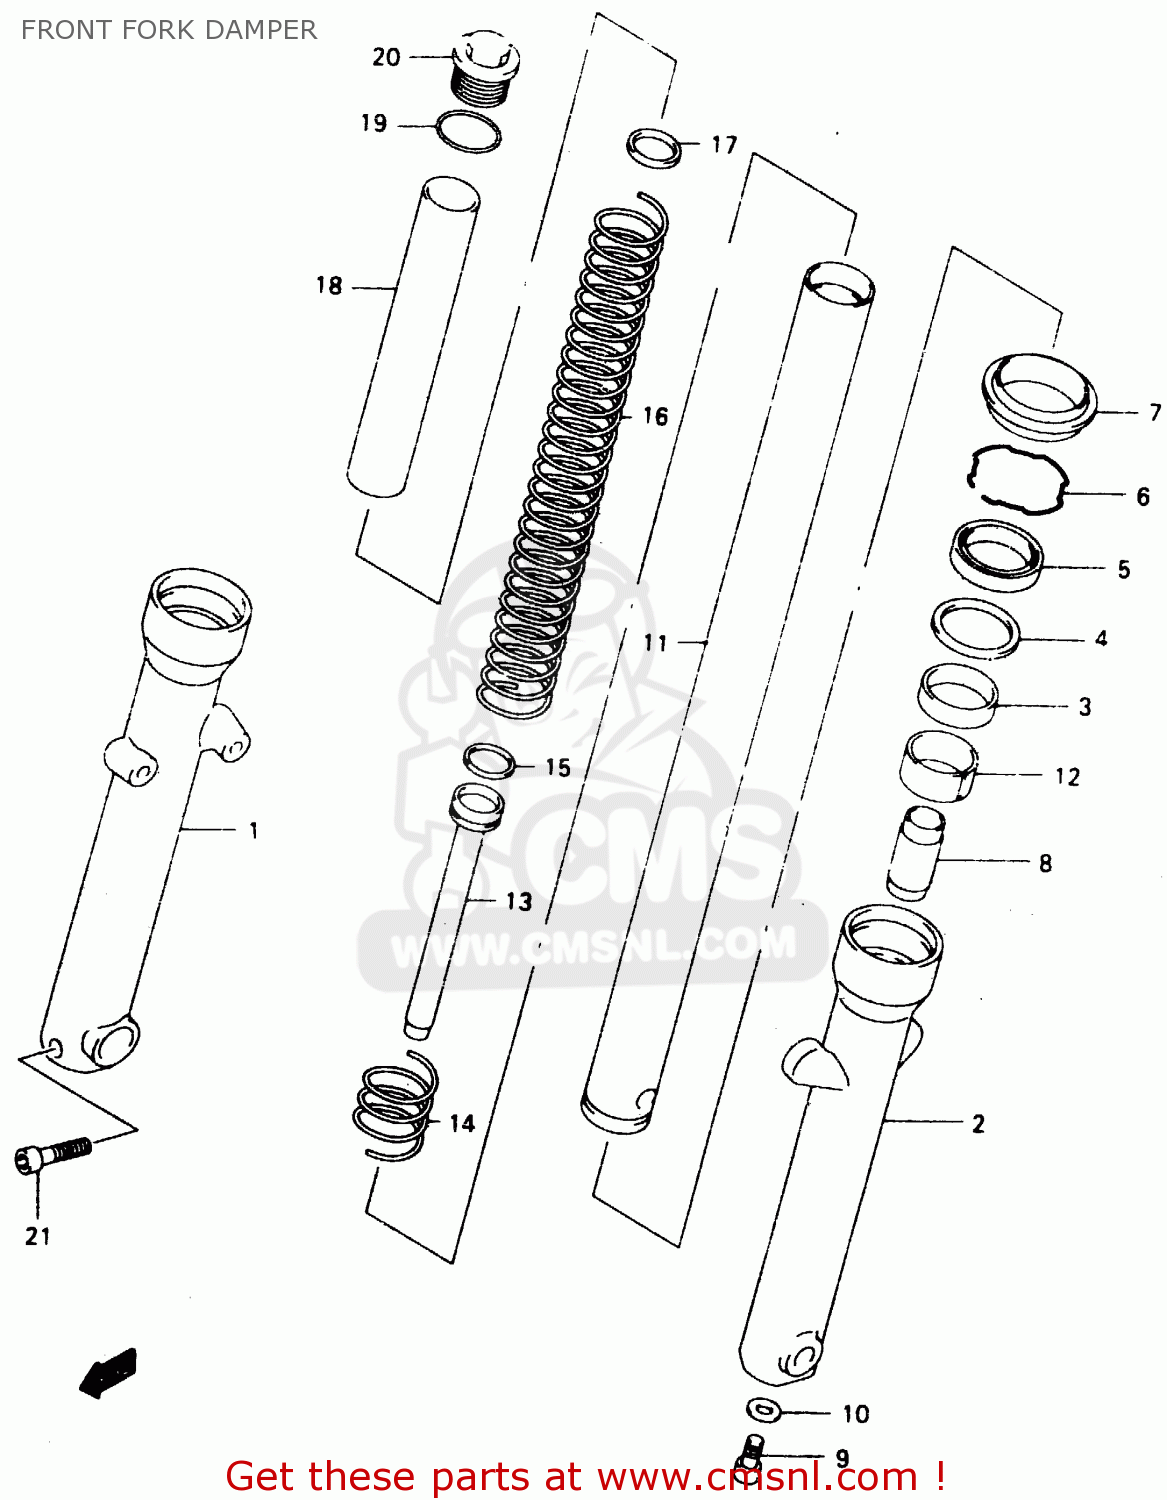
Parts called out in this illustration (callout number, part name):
1	TUBE,OUTER,R
2	TUBE,OUTER,L
3	BUSHING,GUIDE
4	SPACER,SEAL
5	OIL SEAL,FRONT FORK
6	RING,STOPPER
7	SEAL,DUST
8	PIECE,OIL LOCK
9	BOLT,CENTER (8X18)
10	GASKET (NAS)
11	TUBE,INNER
12	BUSHING,SLIDE
13	PIPE,SEAT
14	SPRING,REBOUND
15	RING,PISTON
16	SPRING,FR
17	JOINT,SPRING
18	SPACER,SPRING
19	O RING
20	BOLT,FR FORK
21	BOLT
